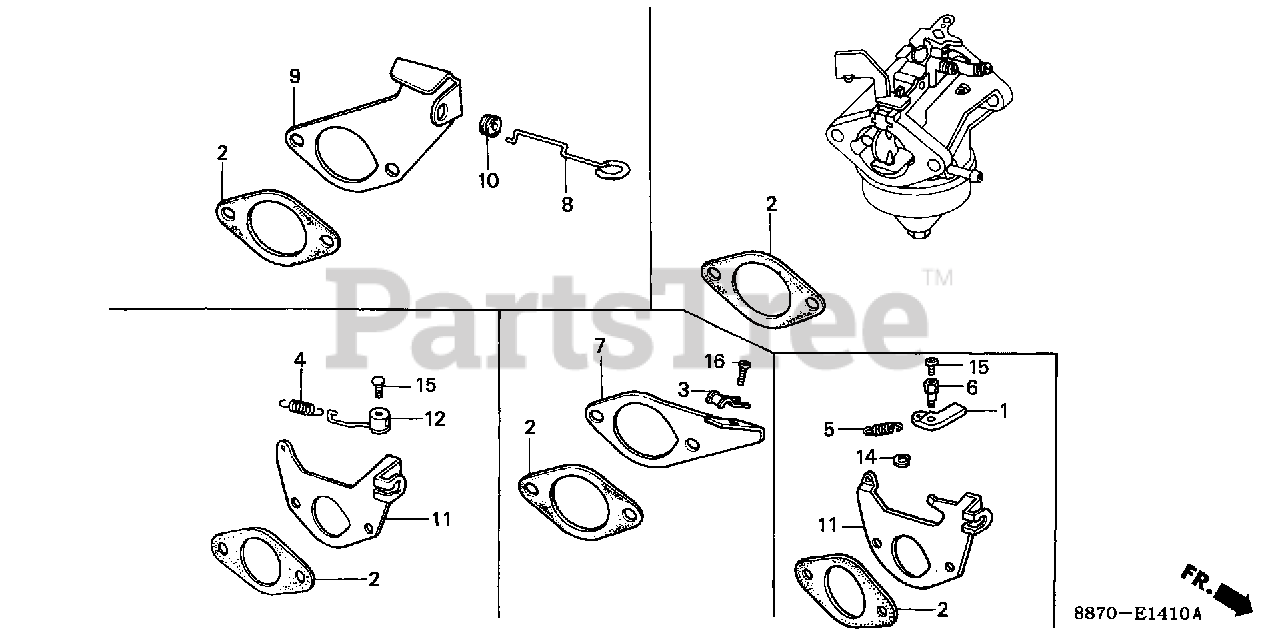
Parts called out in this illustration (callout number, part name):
2	GASKET, AIR CLEANER
8	ROD, CHOKE CONTROL
9	STAY, CHOKE CONTROL
10	GROMMET, CHOKE ROD
